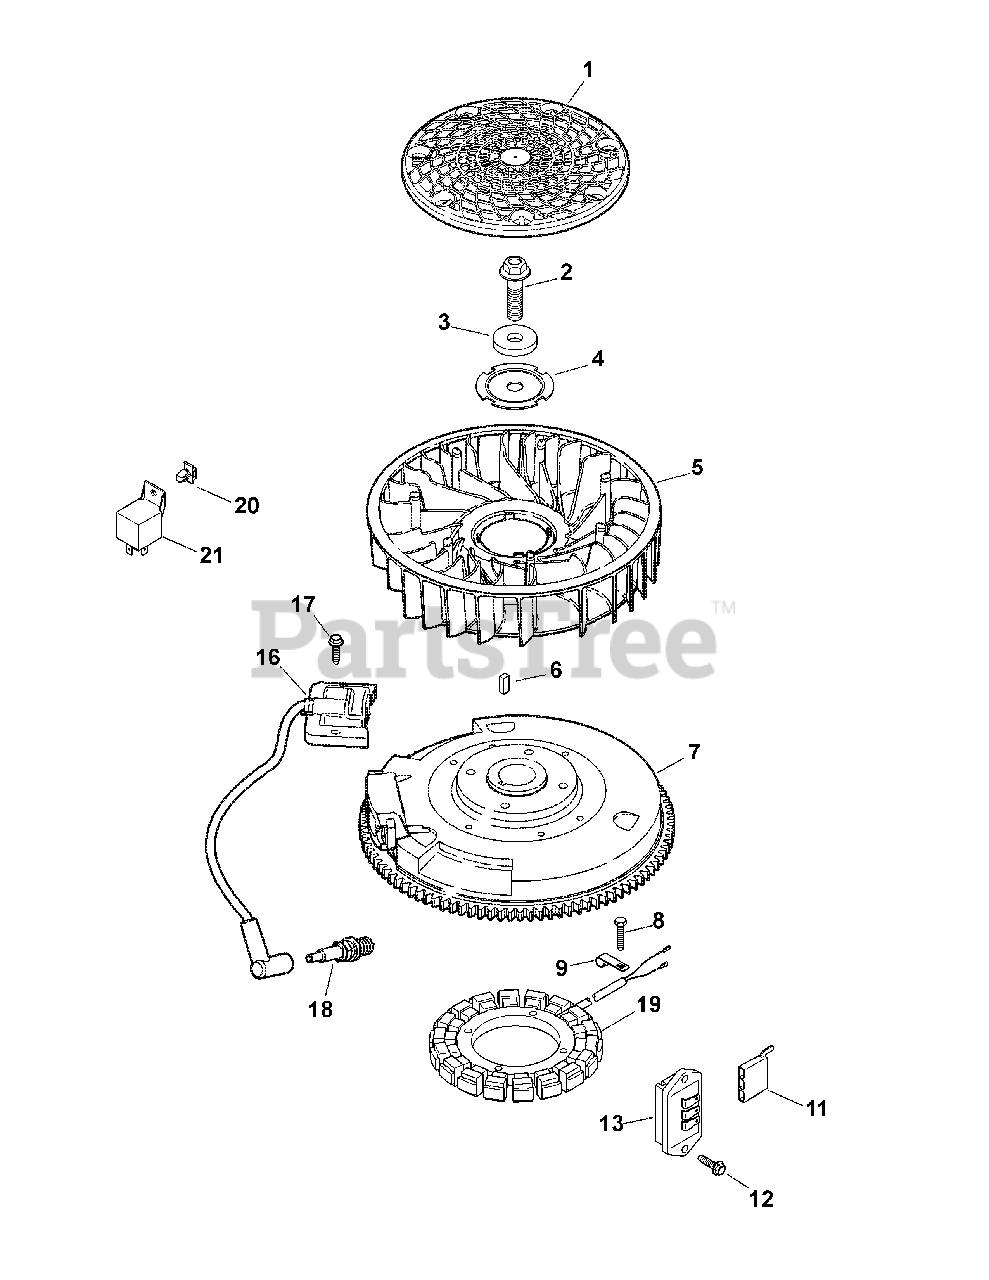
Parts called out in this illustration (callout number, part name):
2	Hex Flange Screw
4	Fan Mounting Plate
6	Straight Flywheel Key
7	Flywheel
8	Thd. Frm. Screw, M5 X 0.8 X 25
10	15 Amp Stator Kit
12	Flg. Thd. Frm. Screw, M5 X .8 X 20
13	Regulator/Rectifier
14	Fuse Block
15	Fuse Block
16	Ignition Module (CDI Fixed)
17	Flg. Thd. Frm. Screw, M5 X .8 X 20
18	Spark Plug
19	Fuse Block
20	Fuse Block
21	Fuse Block
